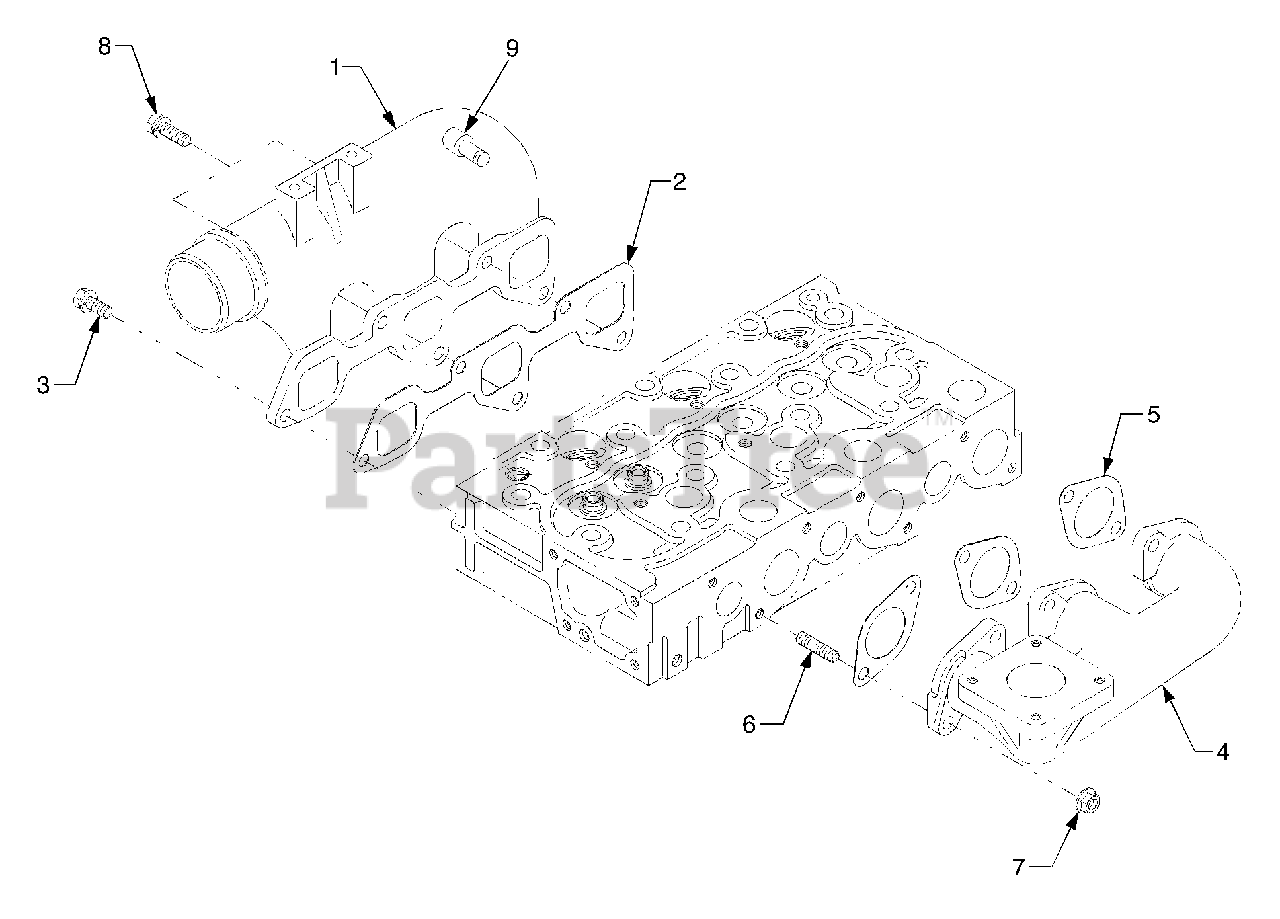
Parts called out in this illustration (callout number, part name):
1	Manifold, Inlet
2	Gasket, Inlet Manifold
4	Manifold, Exhaust
5	Gasket,Exhaust Manifold
9	Connector, Air Breather
